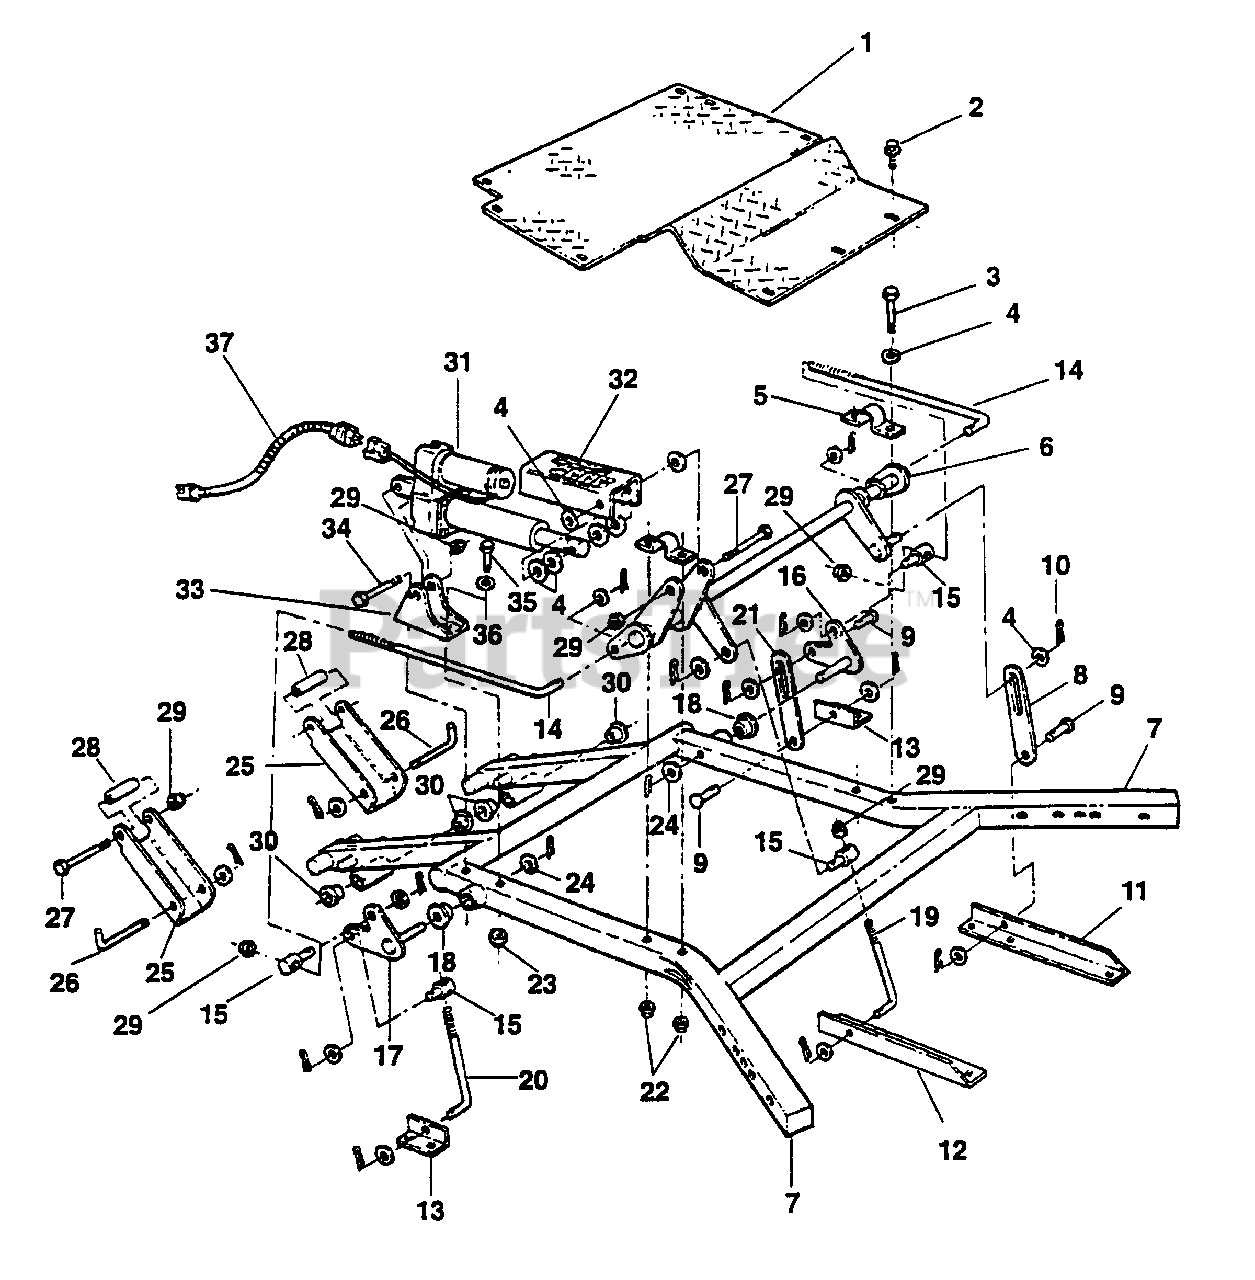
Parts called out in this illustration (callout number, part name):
1	PLATE, Diamond Tread Foot
2	SCREW, 5/16-18 x 5/8" Hex Washer Head, Self-Tapping Swage
3	BOLT, 5/16-18 X 2-1/2" GD5 YZ
4	WASHER, .531 x 1.062 x .121 SAE Flat
5	BRACKET, Deck Lift Hanger
6	ARM, Front Lift (Weldment)
7	FRAME, Deck (Weldment)
8	BAR, 7" Lift
9	PIN, 1/2 x 1 1/8" Clevis (YZ)
10	PIN, 5/32 x 1" Cotter
11	ANGLE, Front Deck Mounting (L.H.)
12	ANGLE, Front Deck Mounting (R.H.)
13	BRACKET, Deck Lift, Rear
14	ROD, Timing, 1/2" Threaded
15	SWIVEL, .50 Thru Hole
16	ARM, Rear Bellcrank (L.H.) (Weldment)
17	ARM, Rear Bellcrank (R.H.) (Weldment)
18	BEARING, .75 I.D.
19	J-BOLT, 1/2" Dia. x 8 1/2" Long (Front)
20	J-BOLT, 1/2" Dia. x 7" Long (Rear)
21	BAR, 5.62 Lift
22	NUT, 5/16-18 HEX NYLON LOCK
23	NUT, 3/8-16 HEX NYLON LOCK
24	WASHER, 13/16 x 1 15/32" (HS)
25	CHANNEL, Deck Stabilizer
26	J-BOLT, Deck Attachment
27	BOLT, 1/2-13 x 4" Hex (HO)
28	SLEEVE, Stabilizer
29	NUT, 1/2-13 HEX NYLON LOCK
30	BUSHING, Suspension
31	LINEAR ACTUATOR, 1000 Lbs., 4" Stroke
32	INDICATOR, Height Of Cut
33	BRACKET, Actuator Anchor
34	SCREW, 1/2 UNC x 2.5 Hex Head Cap (Black Phosphate)
35	BOLT, 3/8-16 X 2-1/2" GD5 CZ
36	WASHER, 3/8" Flat
37	WIRE HARNESS, Deck Lift
